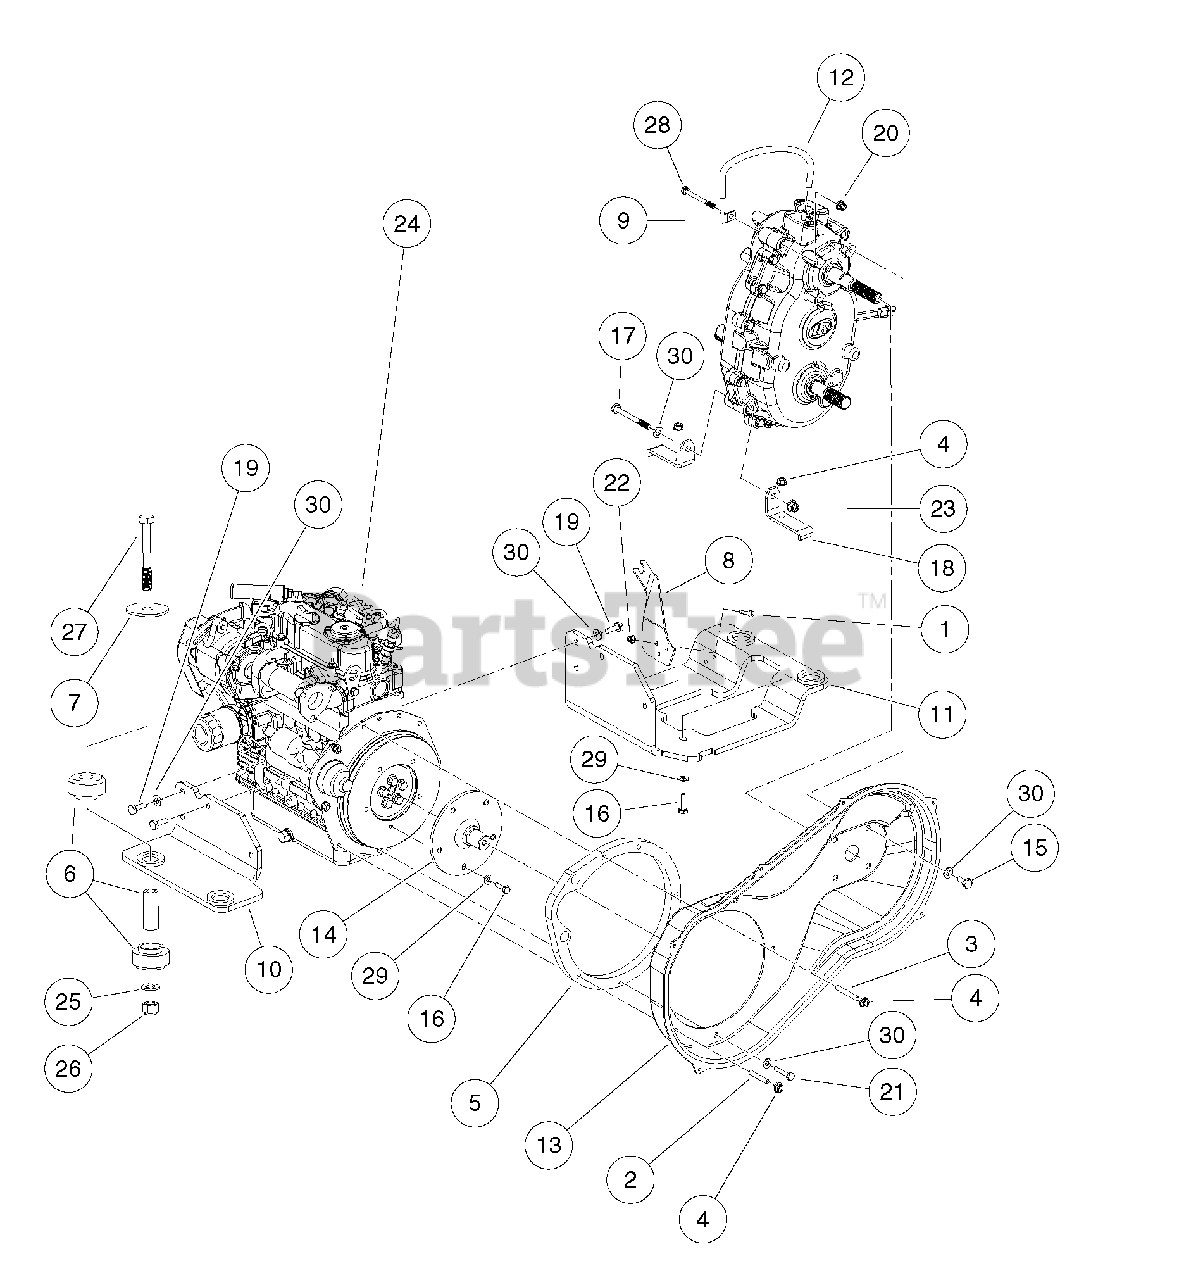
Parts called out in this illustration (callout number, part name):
1	Screw, M6-1.00 X 25mm Hex Cap
2	Stud, M8-1.25 X 50 mm Two-Ended
3	Stud, M8-1.25 X 60mm Two-Ended
4	Nut,m8,all Metal Lock
5	Spacer, Engine, Diesel
6	Isolator Ring and Bushing
7	Washer, Snubbing, Ring N Bush
8	Bracket, FNR Trans Cable
9	P-Clamp, Insulated .312 In
10	Plate, Engine Mounting, Weld, Left-Hand
11	Plate, Engine Mounting, Weld, Right-Hand
12	Hose, Vent, Transmission
13	Cover, CVT Inner, Diesel
14	Shaft, CVT Adapter
15	Bolt, M10 X 1.5 X 20 Loctite
16	Bolt, M8 X 1.25 X 25 Loctite
17	Bolt, M10 X 1.5 X 100 Loctite
18	Bracket, Transmission Mounting
19	Bolt, M10 X 1.25 X 25 Loctite
20	Lock Nut, Flg M8 X 1.25 Nylon
21	Bolt, M8 X 1.25 X 40 with Loctite
22	Nut Flg, M6 X 1.0 Nylon
23	Nut Flg M10 X 1.5 Nylon
24	Engine, Kubota, D722, with Closed Breather, 60a
25	Washer, M12 Hard
26	Locknut, M12x1.75 Nylon Insert
27	Bolt, M12 X 1.75 X 90
28	Bolt, M8 X 1.25 X 80
29	Washer, M8 Hard
30	Washer, M10 Hard
